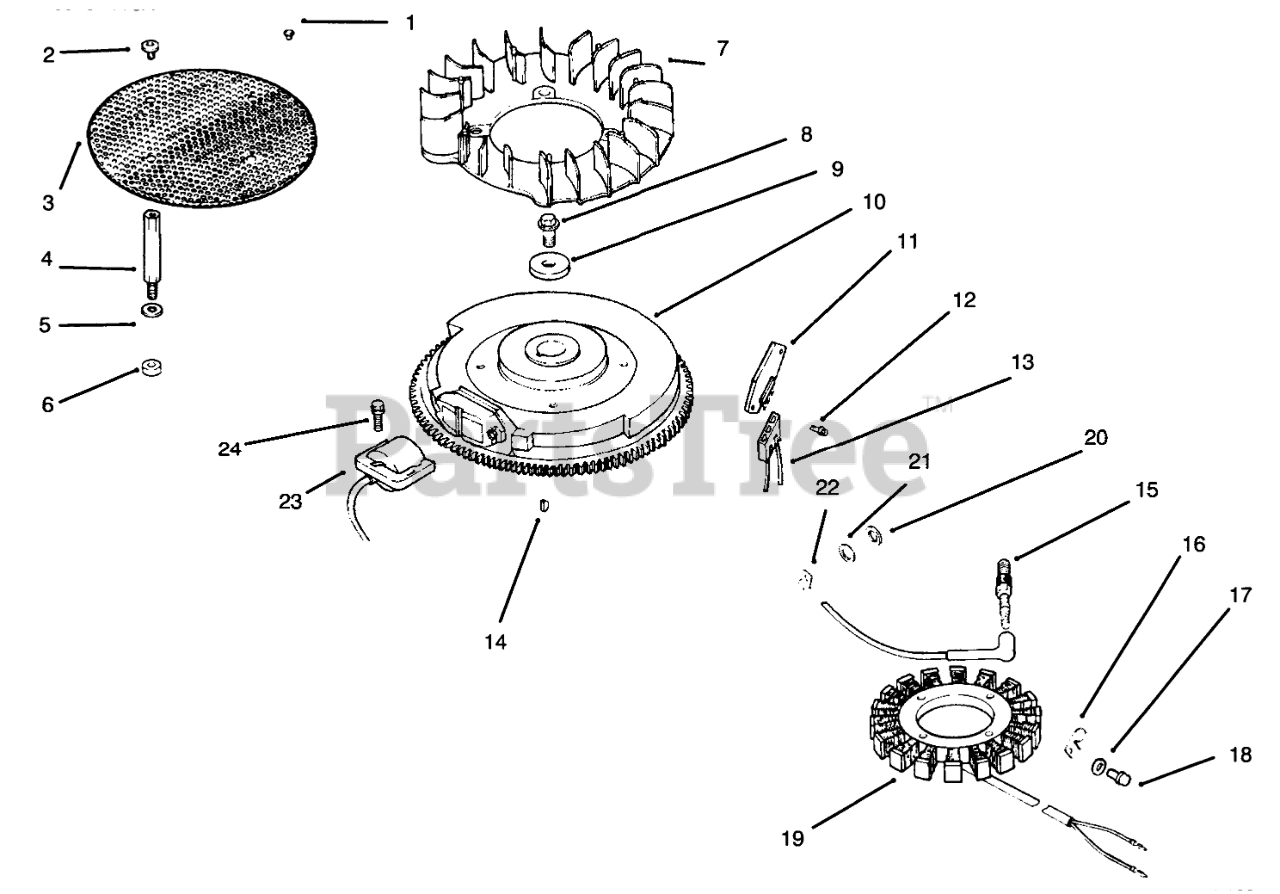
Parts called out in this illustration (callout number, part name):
2	Screw
3	Screen-Grass
4	Stud-Grass Screen
5	Washer
6	Spacer-Fan
8	Screw
10	Flywheel ASM
11	Rectifier-Regulator
13	Connector
14	Key
15	Spark Plug
16	Clip-Cable
17	Washer
18	Screw
19	Stator-15 amp
20	Washer
21	Washer
22	Clip
23	Module-Ignition
24	Screw
